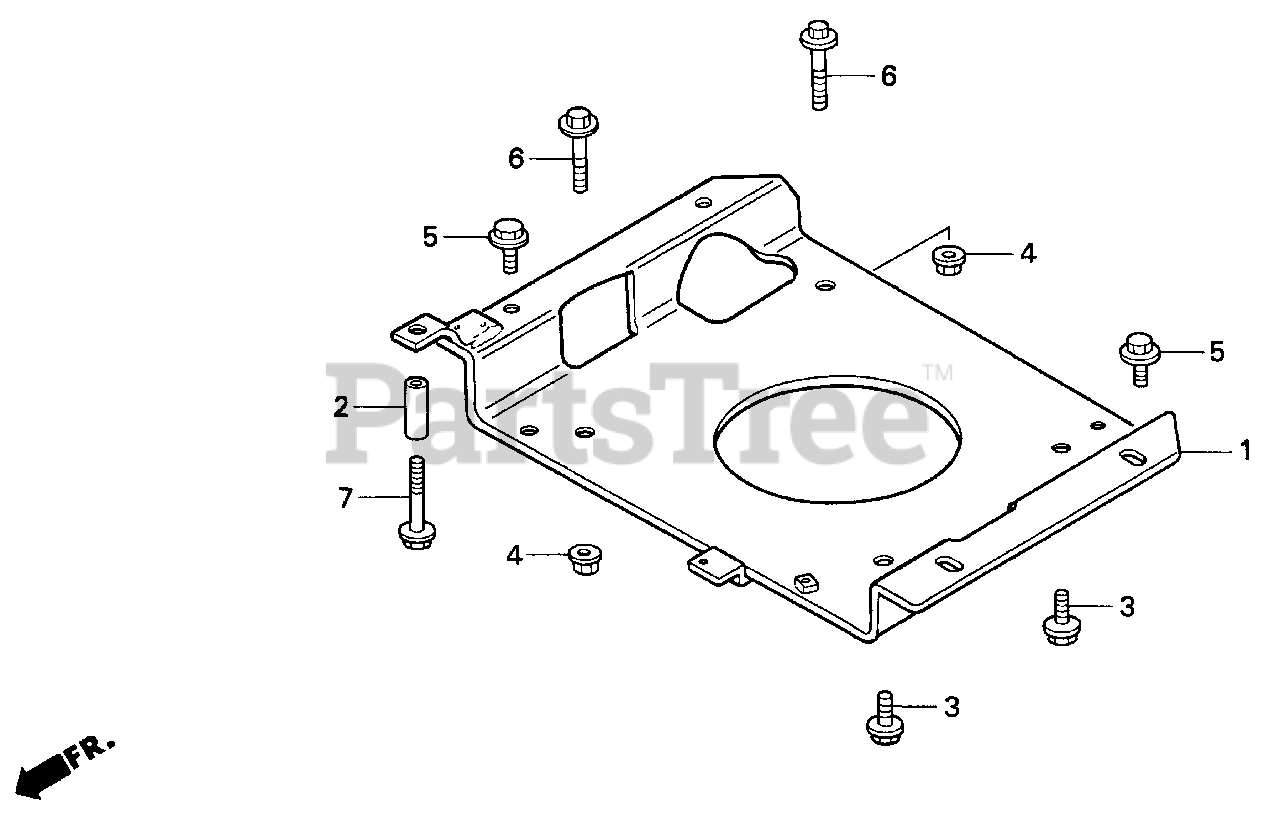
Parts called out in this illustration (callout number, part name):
1	PLATE, ENGINE MOUNTING
2	COLLAR, BELT STOPPER
3	BOLT, FLANGE (5/16"X22)
4	NUT, FLANGE (8MM)
5	BOLT, FLANGE (8X16)
6	BOLT, FLANGE (8X35)
7	BOLT, FLANGE (8X50)
